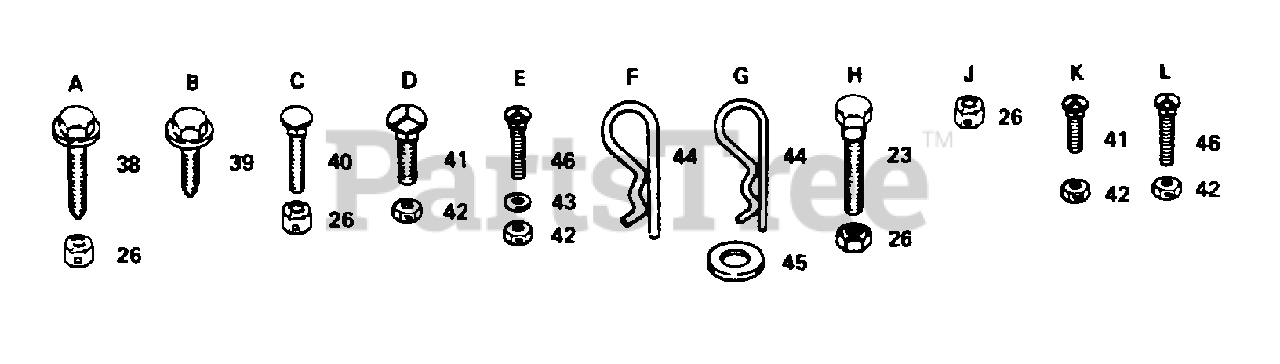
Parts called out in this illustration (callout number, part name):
23	BOLT SHOULDER LTV
38	SCREW
39	SCREW
40	BOLT
41	BOLT
43	WASHER M
46	BOLT
